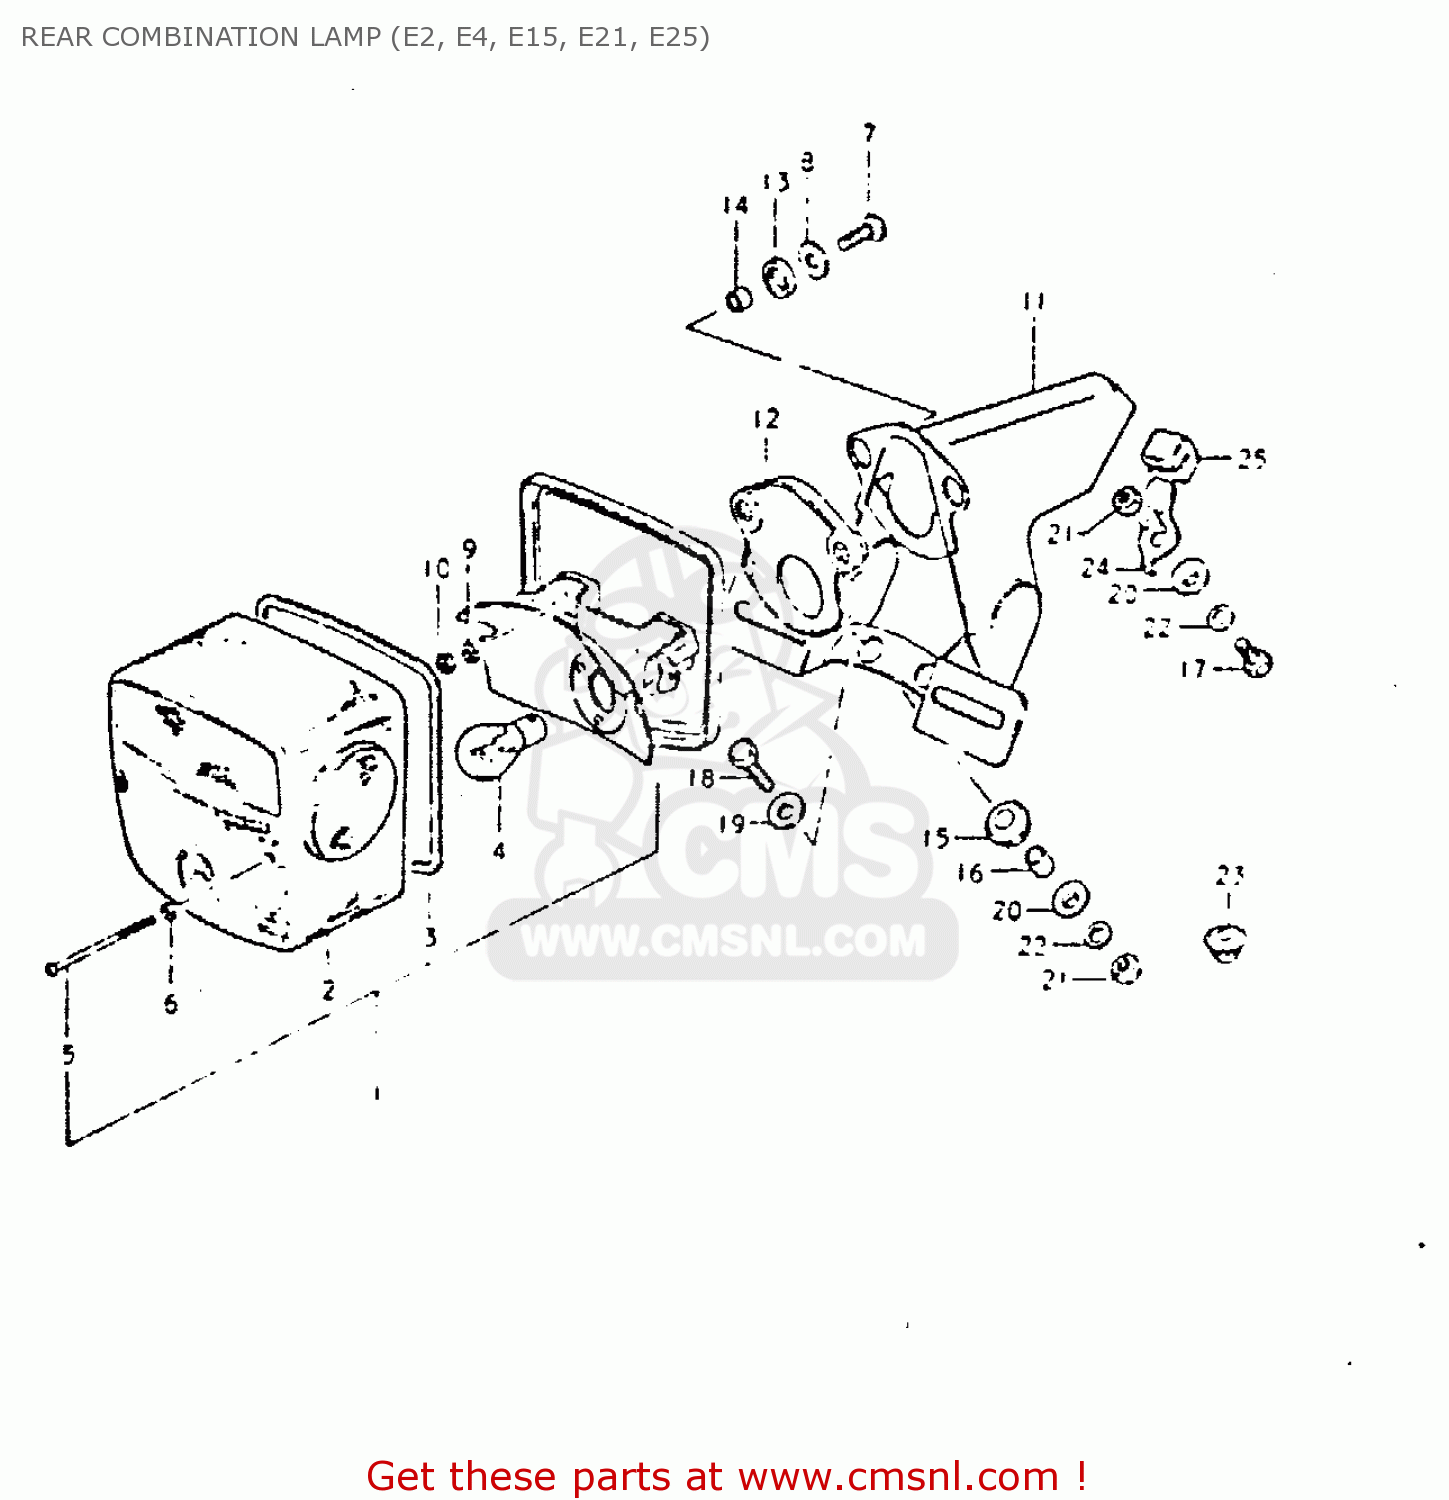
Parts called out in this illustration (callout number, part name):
1	LAMP UNIT, TAIL
2	LENS
3	GASKET (NAS)
4	BULB (6V,21/5W)
5	SCREW (4X55)
6	GASKET (NAS)
7	SCREW
8	WASHER,REAR COMBINATION LAMP
9	NUT
10	LOCK WASHER
11	BRACKET SET
12	CUSHION
13	CUSHION
14	SPACER,REAR COMBINATION LAMP
15	CUSHION,REAR COMBINATION LAMP
16	SPACER
17	BOLT
18	BOLT
19	WASHER (6.5X20X1.2)
20	WASHER
21	NUT
22	WASHER
23	GROMMET
24	PLATE
25	CUSHION
